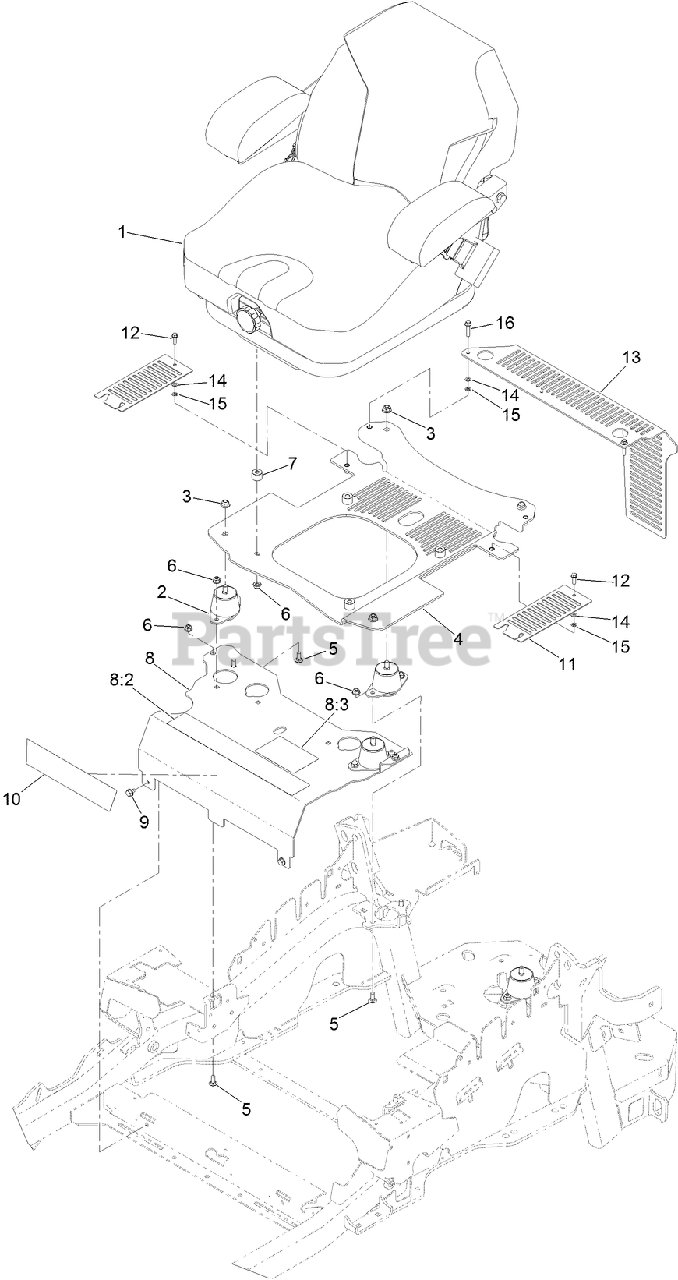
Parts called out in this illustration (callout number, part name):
2	ISOLATOR-SEAT
3	NUT-HF, NI
4	SEAT BASE ASM
5	SCREW-CARR
6	NUT-HF, NI
7	SPACER
8	MOUNT-SEAT
8:2	DECAL-CONSOLE
8:3	DECAL-SERVICE AID
9	SCREW
10	DECAL
12	SCREW-HWH
13	GUARD-CE
14	WASHER-FLAT
15	NUT-RETAINER
16	SCREW-HHF
